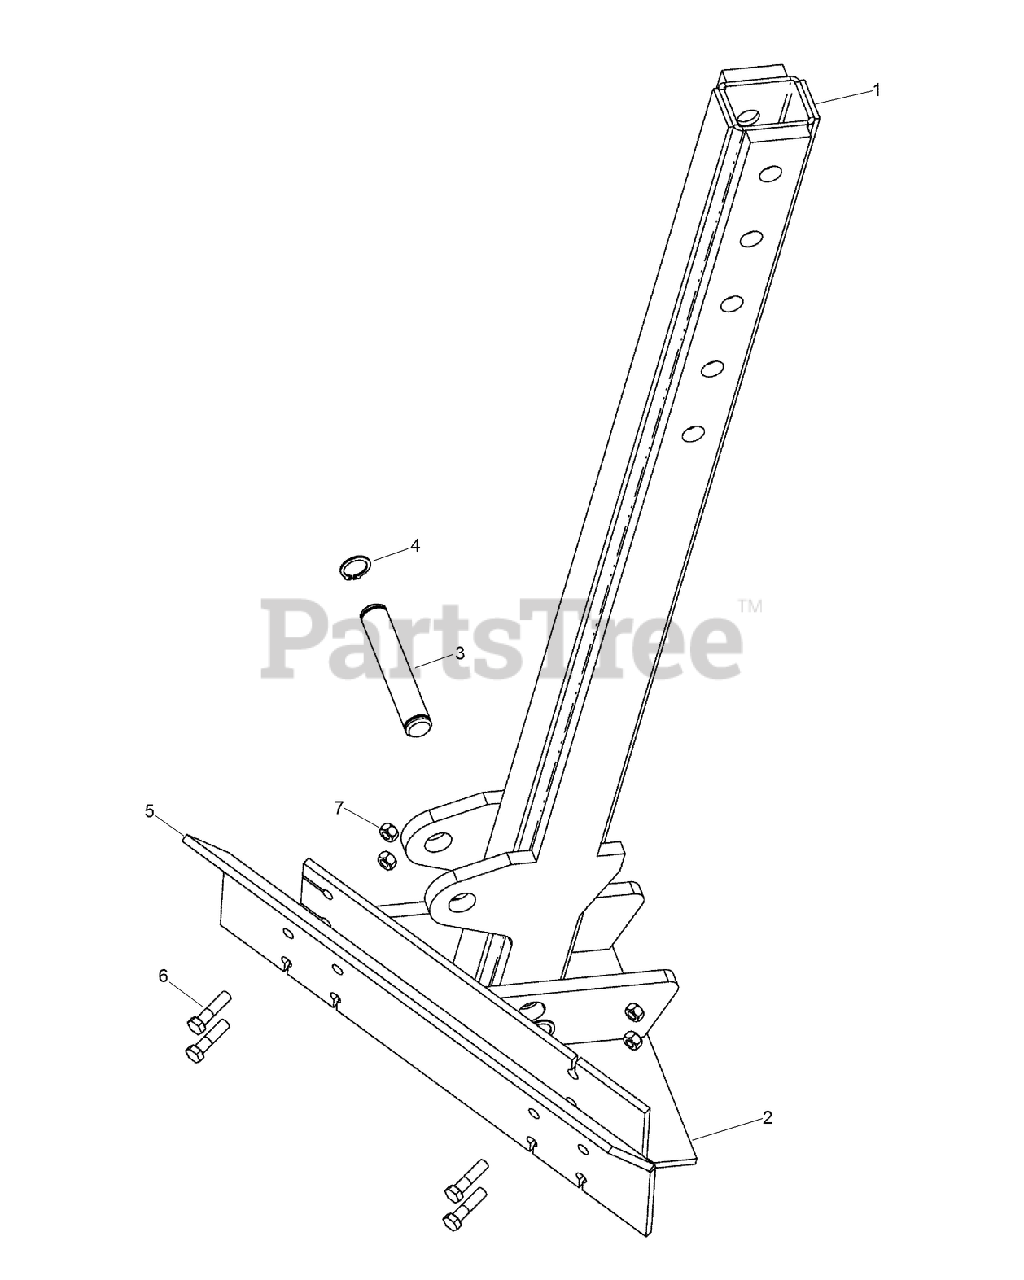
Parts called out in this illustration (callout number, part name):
1	WELDMENT - Stabilizer Bar
2	WELDMENT - Foot, Left-Hand
3	PIN-PIVOT
4	RING-RETAINING
5	PLATE - Berm Scraper
7	NUT-LOCK, HEX
